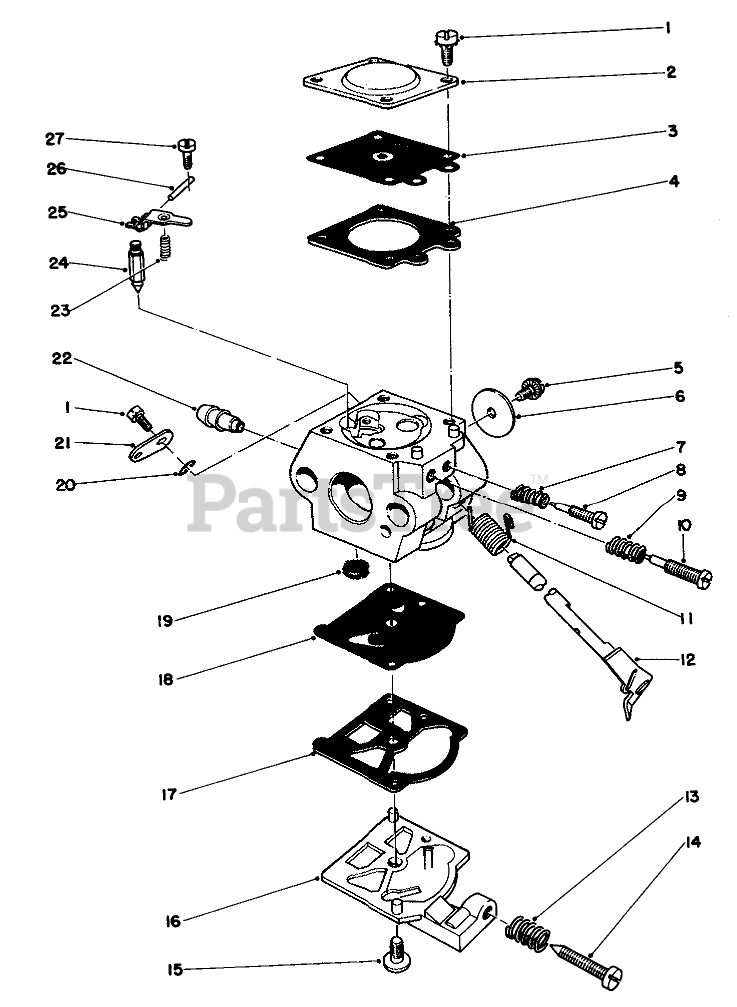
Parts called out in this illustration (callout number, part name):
1	Screw
2	Cover, Diaphragm
3	METERING DIAPHRAGM
4	Gasket-Metering Diaphragm
5	VALVE SCREW
6	Valve-Throttle
7	Spring-Needle (Idle)
8	Needle-Idle
9	Spring-Needle (Hi)
10	Needle Hi Speed
11	Spring-Throttle Return
12	Shaft Assembly-Throttle
13	Spring-Idle Screw
14	Screw-Idle Adjust
15	Screw
16	Cover-Fuel Pump
17	PUMP GASKET
18	PUMP DIAPHRAGM
19	Inlet Screen
20	Ring-Throttle Retainer
21	Lever-Throttle
22	Fitting Fuel Inlet
23	Metering Lever Spring
24	NEEDLE VALVE
25	Lever Metering
26	Metering Lever Pin
27	Screw-Metering Pin
